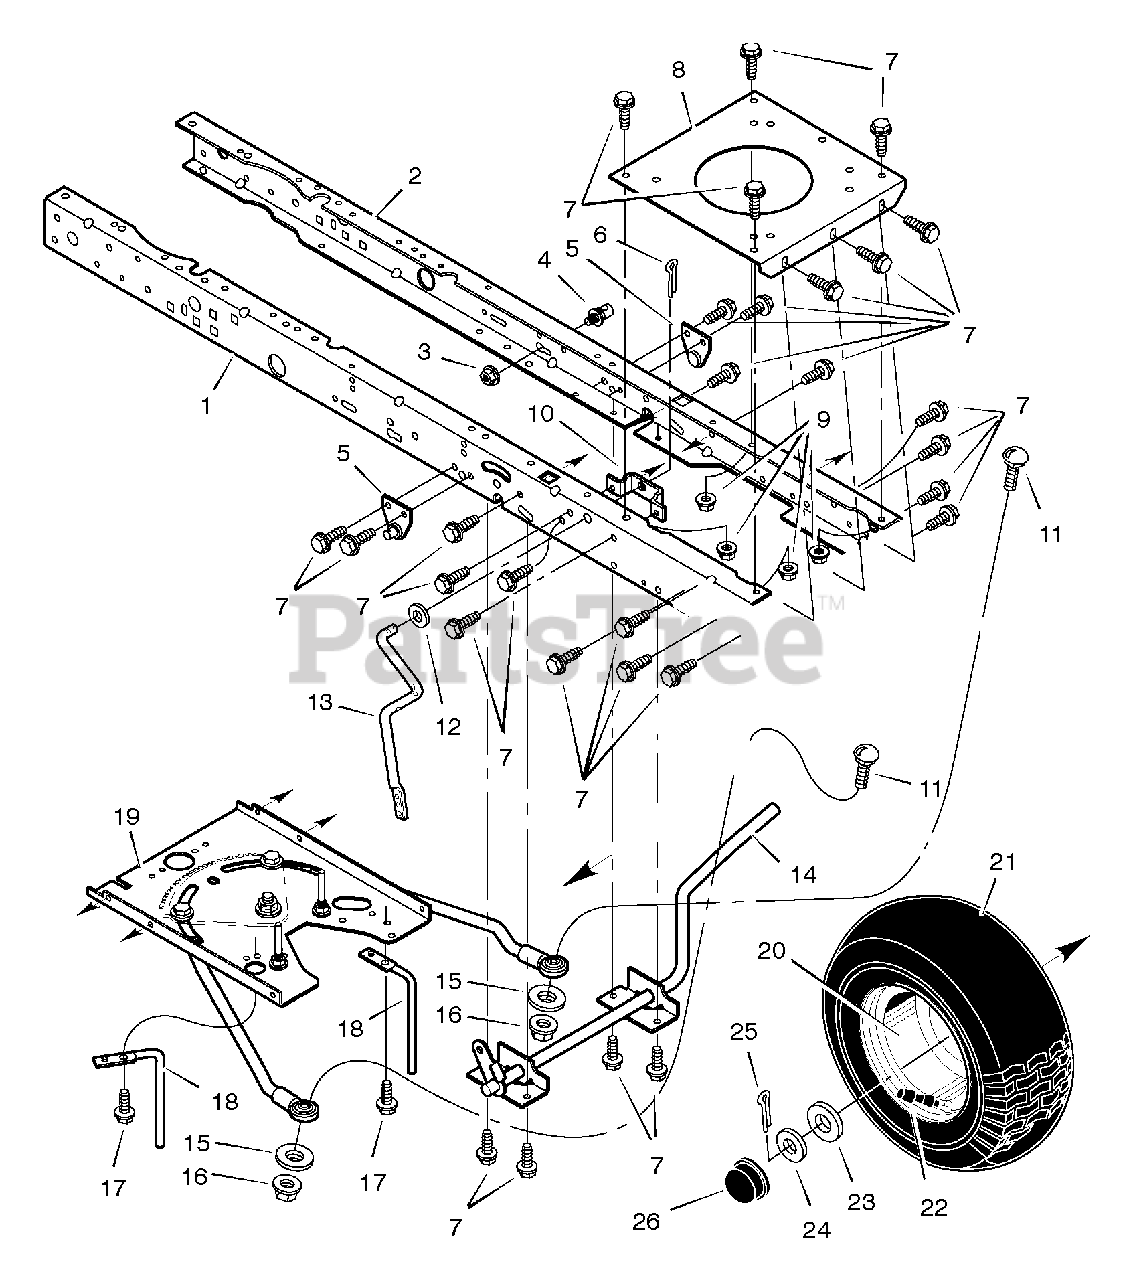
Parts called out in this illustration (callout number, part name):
1	Frame, Right
2	Frame, Left
3	Nut, Flange
4	Stud, Swivel
5	Bracket Ass'y, Suspension
6	Pin, Cotter
8	Plate, Engine
9	Nut
10	Bracket, PTO Crank
11	Bolt, Carriage
13	Crank, PTO
14	Lever, Brake/Clutch
15	Washer
17	Screw
18	Guide, Belt
19	Assembly, Steering *
20	Wheel & Tire Assembly
22	Stem, Valve
25	Pin, Cotter
26	Cap, Hub
